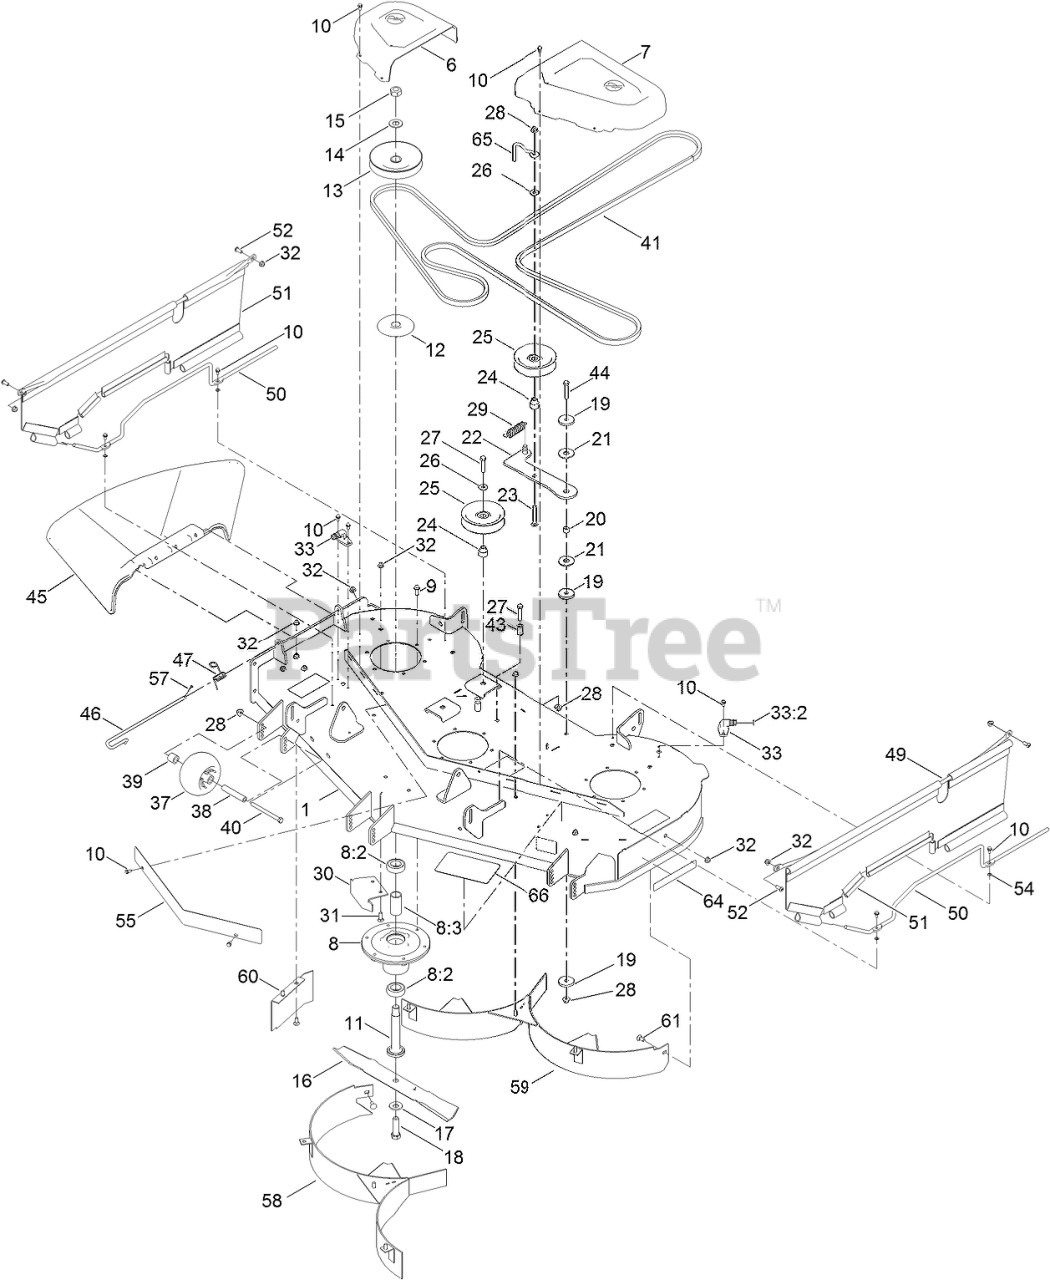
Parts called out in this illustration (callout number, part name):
1	DECK ASM
6	COVER-BELT, RH
7	COVER-BELT, LH
8	SPINDLE ASM
8:2	BEARING-BALL
8:3	SPACER-BEARING
9	SCREW-TAPTITE
10	SCREW-HWH
11	SHAFT-SPINDLE
12	SHIELD-BEARING
13	PULLEY
14	WASHER
15	NUT-HEX
16	BLADE-MULCH, 18.75 INCH
17	WASHER-BELLEVILLE
18	SCREW-BLADE
19	WASHER-PLAIN
20	BUSHING-LEVER, LIFT
21	WASHER-FRICTION, COMPOSITE
22	ARM-IDLER
23	SCREW-CARR
24	BUSHING-IDLER
25	PULLEY-IDLER, FLAT
26	WASHER-HARDENED
27	SCREW-HH
28	NUT-HF, NI
29	SPRING-EXTENSION
30	BAFFLE-CUTOFF
31	SCREW-CARR
32	NUT-HF, NI
33	FITTING-WASHOUT
33:2	O-RING
37	ROLLER-SCALP, ANTI
38	TUBE-SPANNER
39	SPACER-AXLE, REAR
40	SCREW-HH
41	V-BELT
43	SPACER
44	SCREW-HH
45	DEFLECTOR-DISCHARGE
46	PIN-CHUTE
47	SPRING-TORSION
49	ROD SUPPORT, UPPER
50	ROD SUPPORT, LOWER
51	SIDE GUARD ASM
52	SCREW-HSBH
54	NUT-RETAINING
55	SHIELD-FRONT
57	PIN-COTTER
58	BAFFLE-RECYCLER
59	BAFFLE-RECYCLER, LH
60	GUARD-BAFFLE
61	BOLT-CARR
64	DECAL-RECYCLER
65	GUIDE-BELT, IDLER
66	TREAD-STEP
